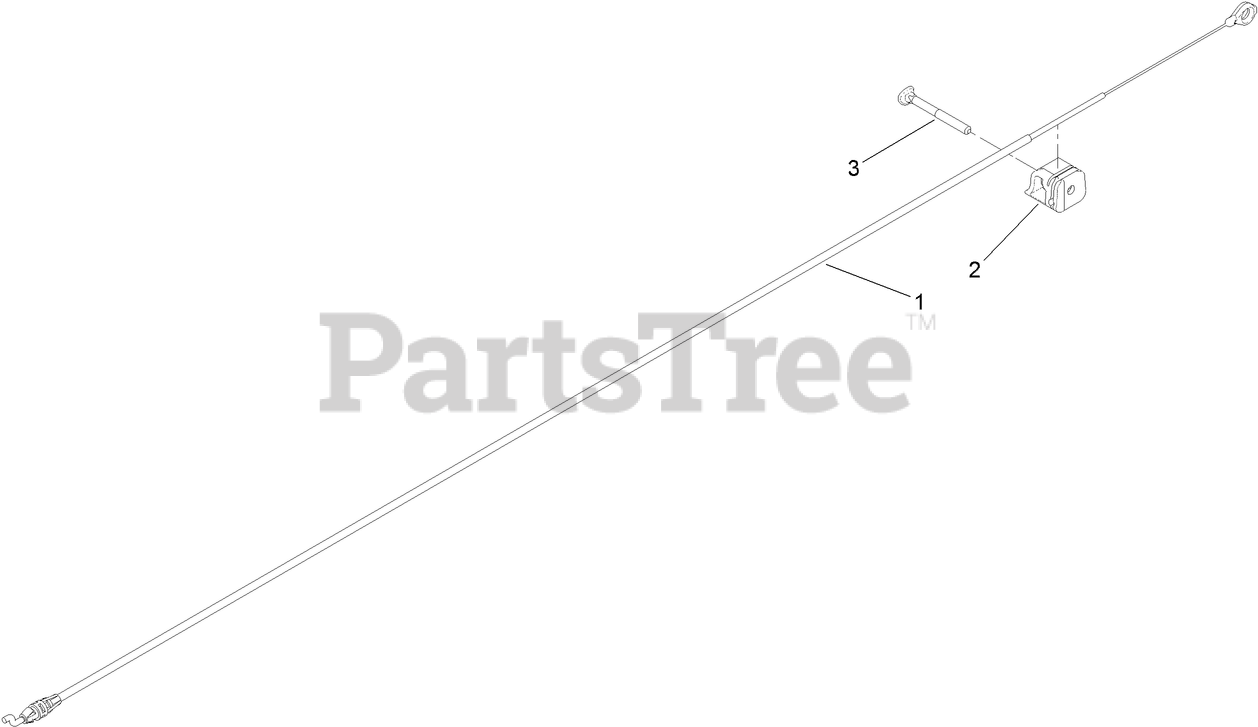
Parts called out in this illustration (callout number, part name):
1	CABLE-BRAKE
2	ANCHOR-CABLE
3	SCREW-HANDLE
